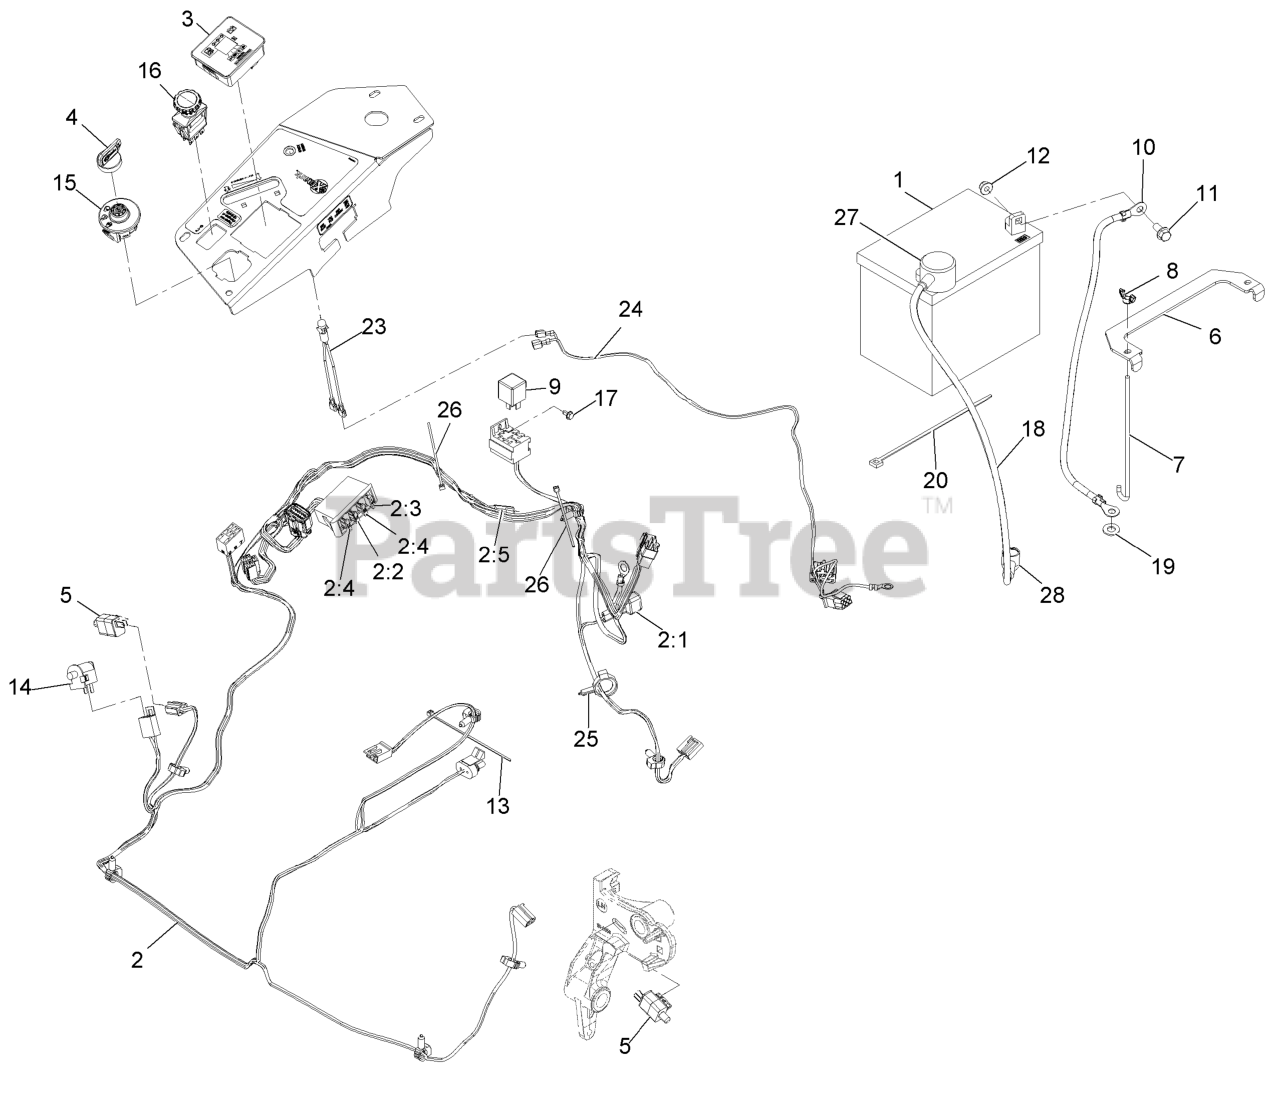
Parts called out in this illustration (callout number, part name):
1	Battery
2	HARNESS-WIRE, MAIN
2:2	FUSE-BLADE, 10 AMP
2:3	FUSE-BLADE, 15 AMP
2:4	FUSE-BLADE, 25 AMP
2:5	CAP-PLUG
3	FUEL/HOUR METER ASM
4	KEYS-IGNITION (SPARE PAIR
4	KEY-IGNITION
6	STRAP-TIE DOWN, BATTERY
7	BOLT-HOLDDOWN
8	WINGNUT
10	CABLE-BATTERY, NEGATIVE
11	SCREW-HHF
12	NUT-HF, NI
13	TIE-CABLE
14	SWITCH-BAIL
16	SWITCH-PTO, 10 AMP
17	SCREW-HWH
18	CABLE-BATTERY, POSITIVE
19	WASHER-FLAT
20	TIE-PLASTIC
23	INDICATOR-LED, RED
24	HARNESS-LIGHT, INDICATOR
25	CLAMP-HOSE
26	TIE-CABLE
27	INSULATOR-BATTERY
28	INSULATOR-SOLENOID
